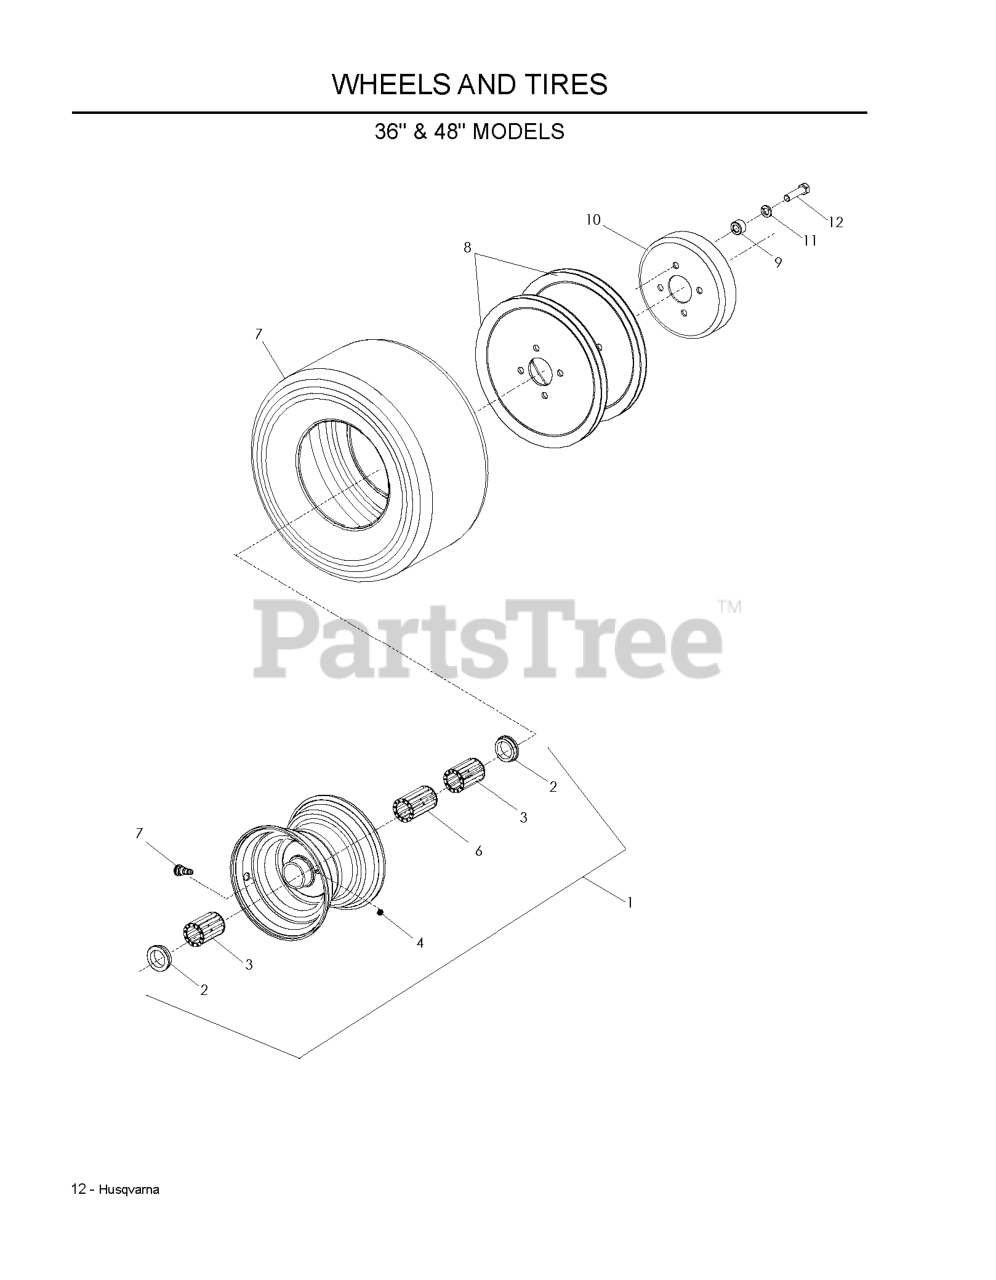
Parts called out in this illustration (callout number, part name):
1	WHEEL.ASM.13X6.5-6.SILVER.COMM
2	BEARING FLANGE
3	ROLLER BEARING (SHORT)
4	ZERK
5	ROLLER BEARING (LONG)
6	VALVE STEM TR-412
7	TRACTION PULLEY
9	BRAKE DRUM
10	SLW 3/8 STD
11	HCS 3/8F X 1 1/2
